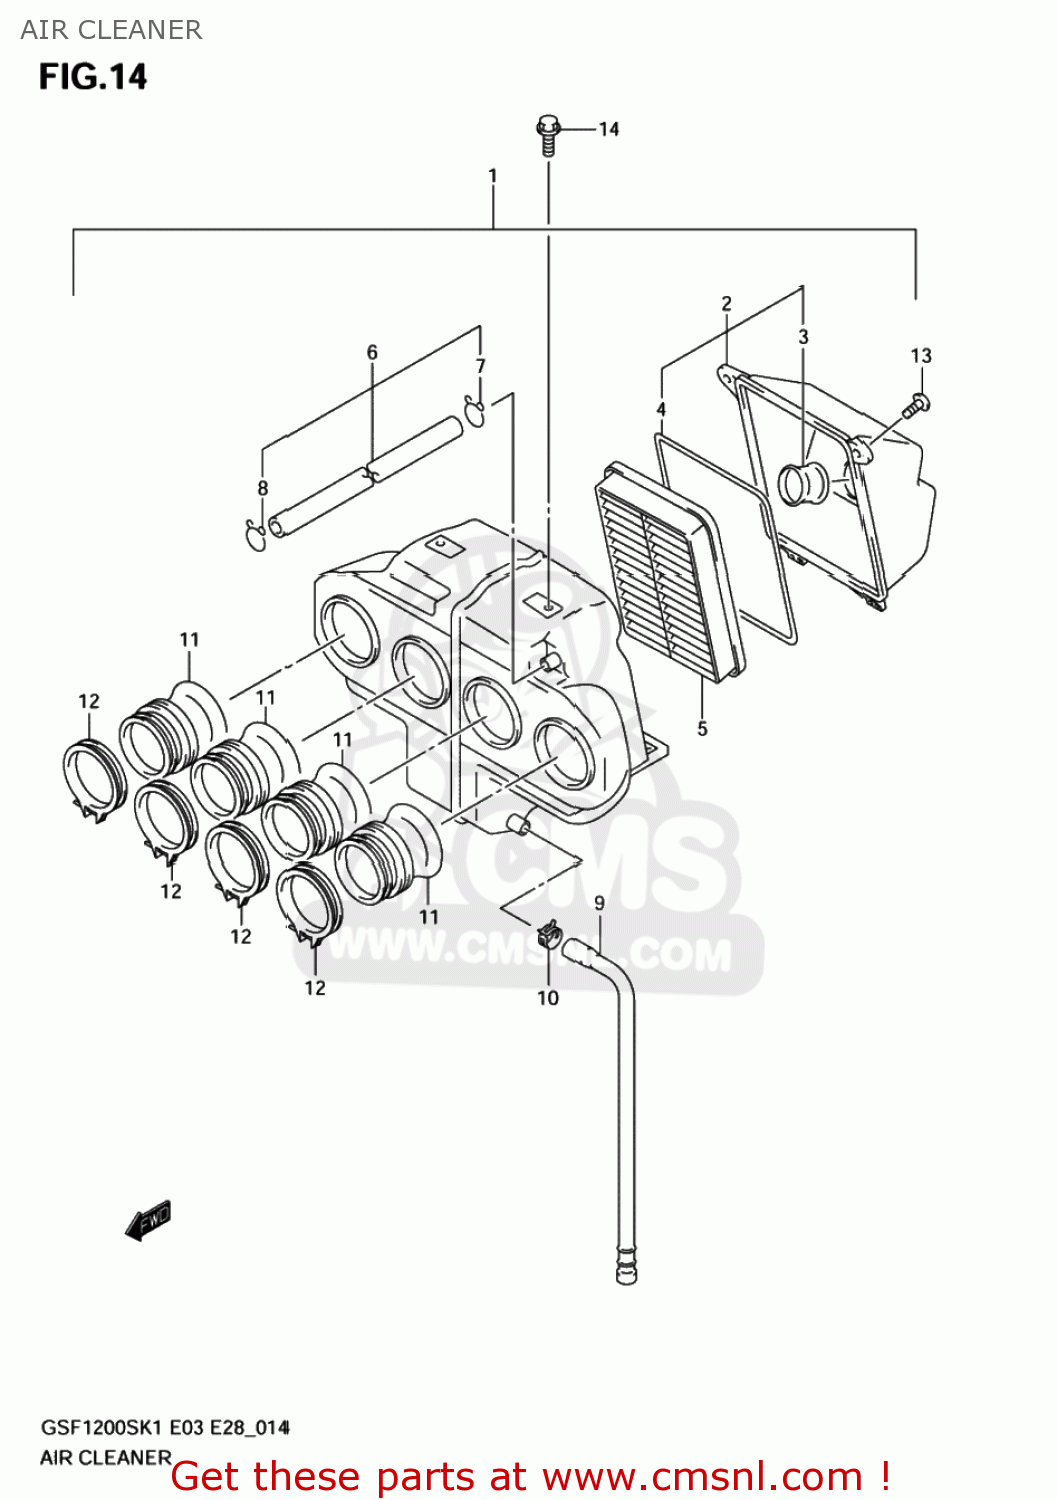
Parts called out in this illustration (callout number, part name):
1	CLEANER ASSY,AIR
2	CAP,AIR CLEANER
3	TUBE,INLET
4	GASKET,AIR CLEANER CAP (NAS)
5	FILTER,AIR
6	TUBE,BREATHER
7	CLIP
8	CLIP
9	TUBE,DRAIN
10	CLIP
11	TUBE,OUTLET
12	CLAMP
13	SCREW 5X12
14	BOLT
